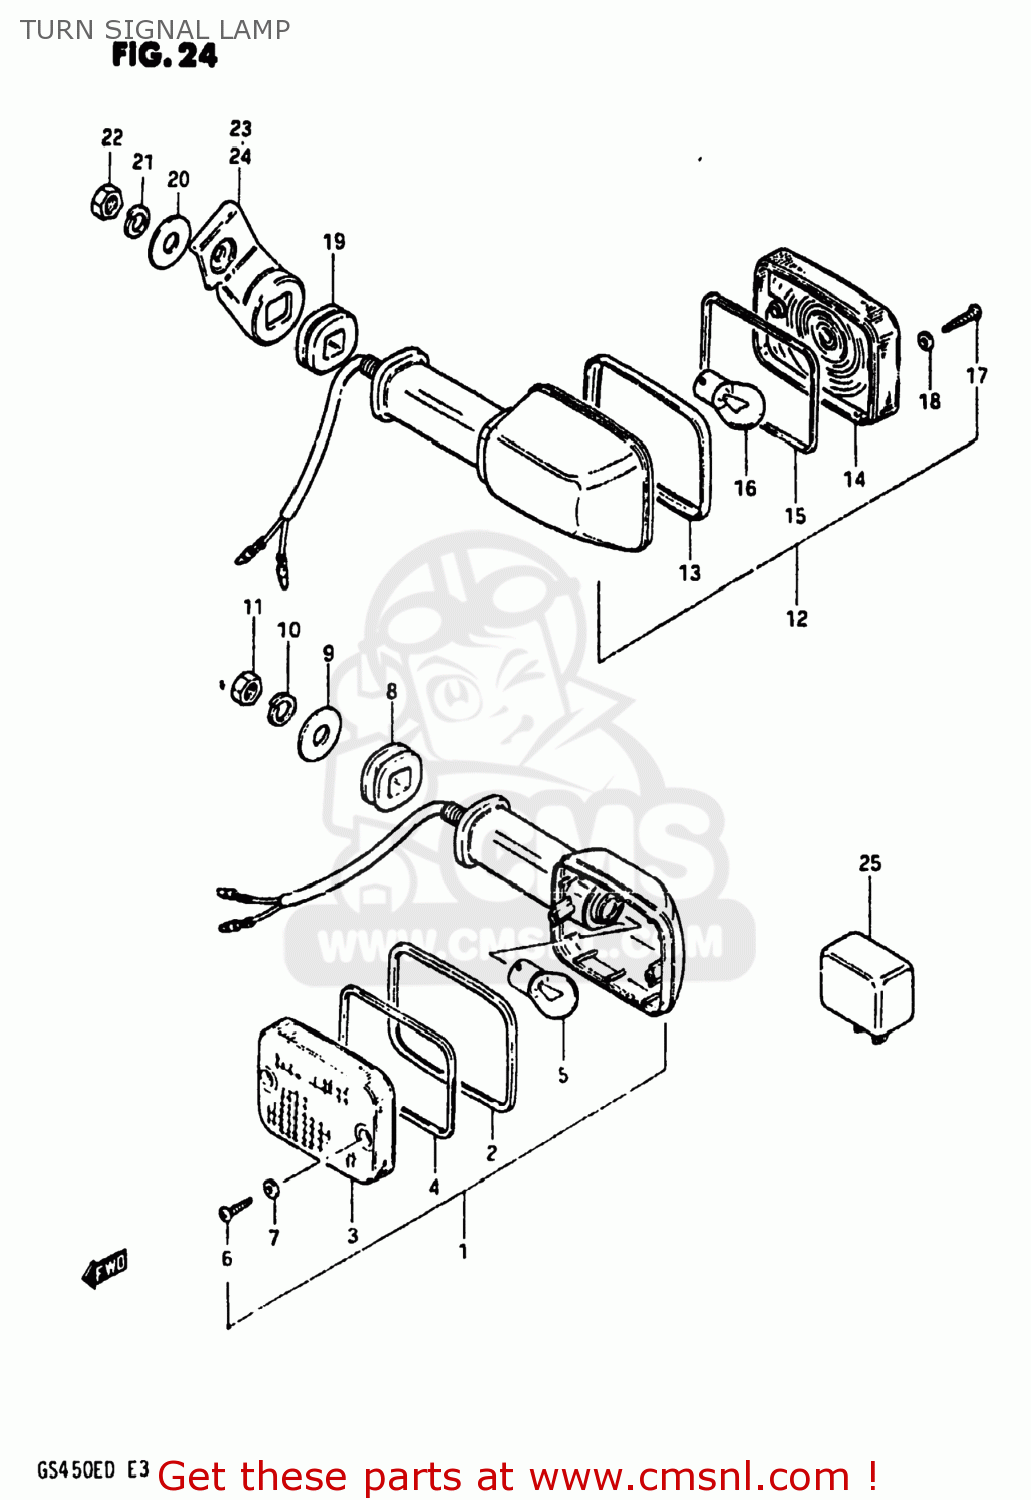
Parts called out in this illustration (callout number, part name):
1	LAMP ASSEMBLY,FRONT TURN SIGNAL
2	RIM
3	LENS
4	GASKET (NAS)
5	BULB(12V23W,STANLEY,A4577A)
6	SCREW
7	GASKET (NAS)
8	CUSHION
9	WASHER (10.5X30X2.3)
10	LOCK WASHER
11	NUT
12	LAMP ASSEMBLY,FRONT TURN SIGNAL
13	RIM
14	LENS
15	GASKET (NAS)
16	BULB(12V23W,STANLEY,A4577A)
17	SCREW
18	GASKET (NAS)
19	CUSHION
20	WASHER (10.5X30X2.3)
21	LOCK WASHER
22	NUT
23	BRACKET,REAR TURN SIGNAL
24	BRACKET,REAR TURN SIGNAL
25	RELAY,TURN SIGNAL
